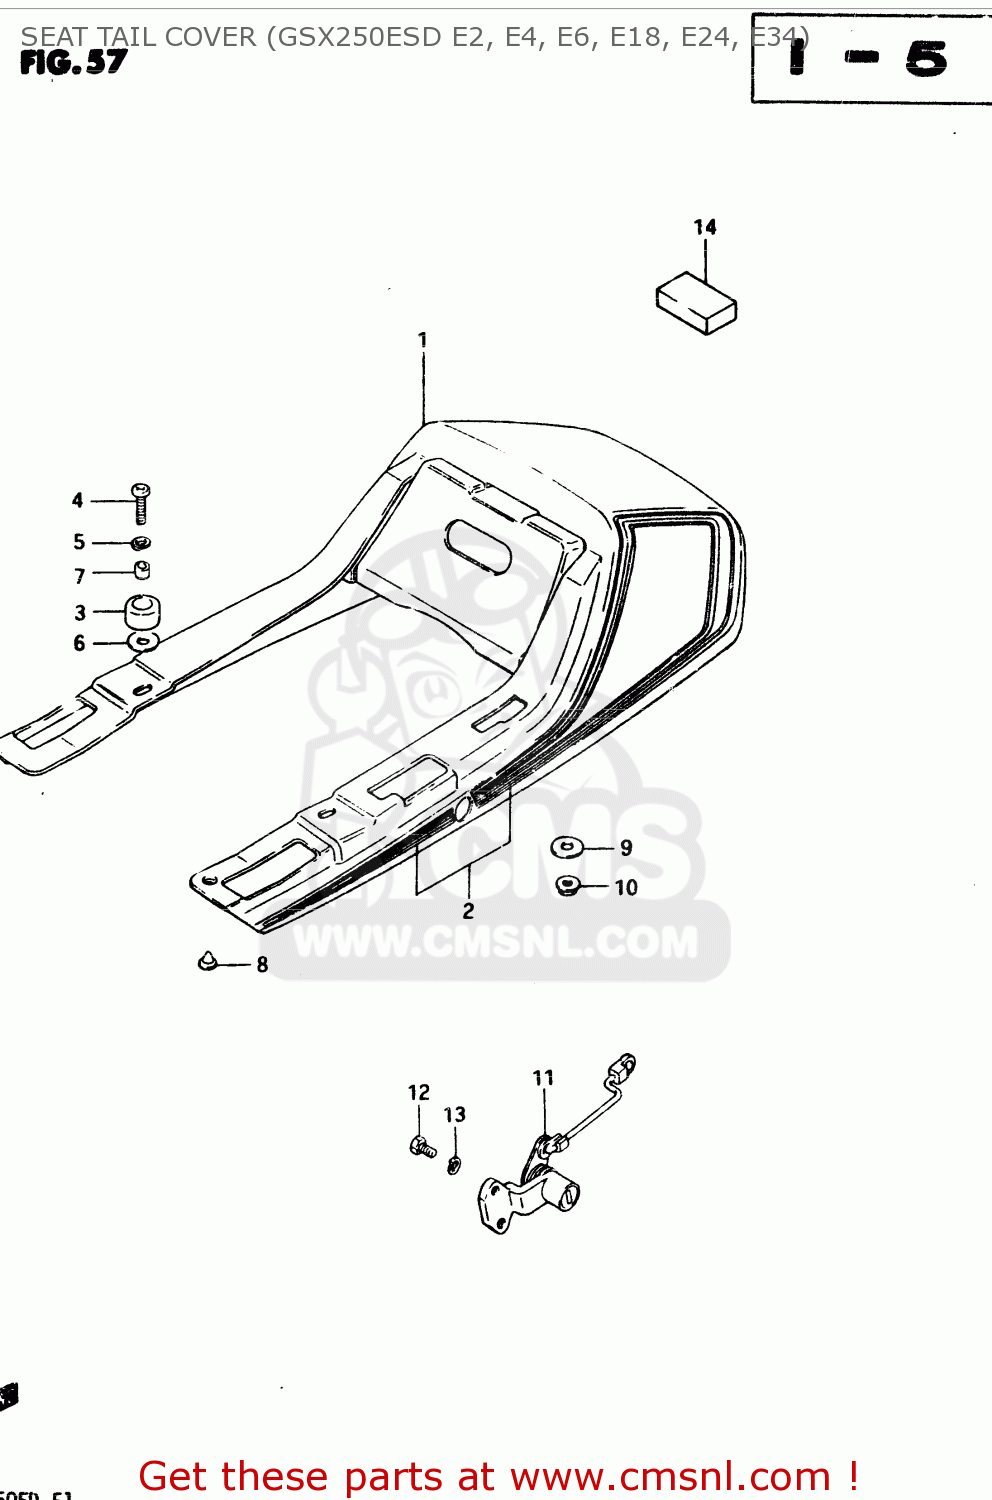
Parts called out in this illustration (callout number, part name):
1	TAIL COVER, SEAT (SILVER)
2	TAPE SET, SEAT TAIL COVER
3	CUSHION,COVER
4	SCREW
5	LOCK WASHER
6	WASHER (6.5X24X1.6)
7	SPACER
8	CUSHION
9	WASHER
10	NUT 6MM
11	LOCK ASSEMBLY,SEAT
12	BOLT 5X10
13	LOCK WASHER
14	CUSHION
